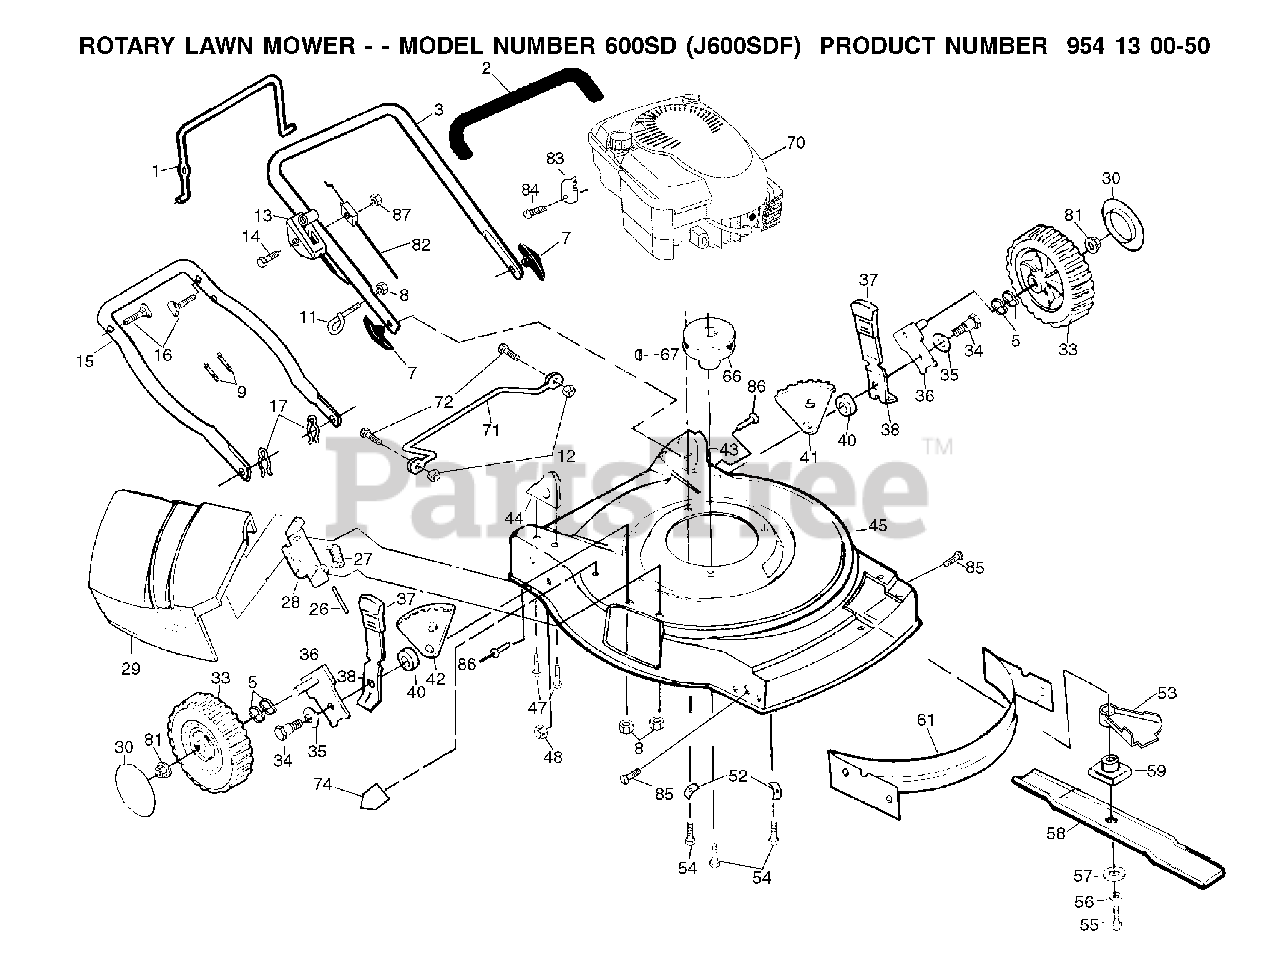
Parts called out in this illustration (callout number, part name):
1	CONTROL BAR ORANGE
2	GRIP.HANDLE.FOAM
5	WAVE WASHER
7	HANDLE KNOB
8	NUT
9	TIE GUIDE
11	ROPE, GUIDE
13	THROTTLE CONTROL
14	SCREW 1/4-20 X 2.12
15	LOWER HANDLE
16	HANDLE BOLT
17	HAIRPIN COTTER
26	ROD.HINGE.COMBI-C
27	SPRING PM
28	BRACKET PM
33	WHEEL.8X2.PR.LP.RAD.GREY
34	BOLT
35	BELLEVILLE WASHER
36	AXLE ARM
37	SELECTOR KNOB
40	RP SPACER HT ADJ
43	HANDLE BRACKET ASM. LH
44	HANDLE BRACKET ASM. RH
47	SCREW 5/16-18
48	LOCKNUT PM
53	DEBRIS SHIELD
54	BOLT 3/8-16X1-1/8
55	SCREW, HEX HD 3/8-24 X 1-3/8
56	LOCKWASHER
57	WASHER,HARDEN
59	RP BLADE ADAPTOR
66	ENGINE.PULLEY.FWG
67	HI PRO KEY PM
74	DECAL MOWER CUT/FINGER
81	HEX FLANGE LOCKNT
82	ENGINE ZONE CONTROL
83	CABLE CLAMP(ENGINE)
84	SCREW.HEX.HEAD.WASHER.10-16
86	RIVET BLIND
87	NUT
